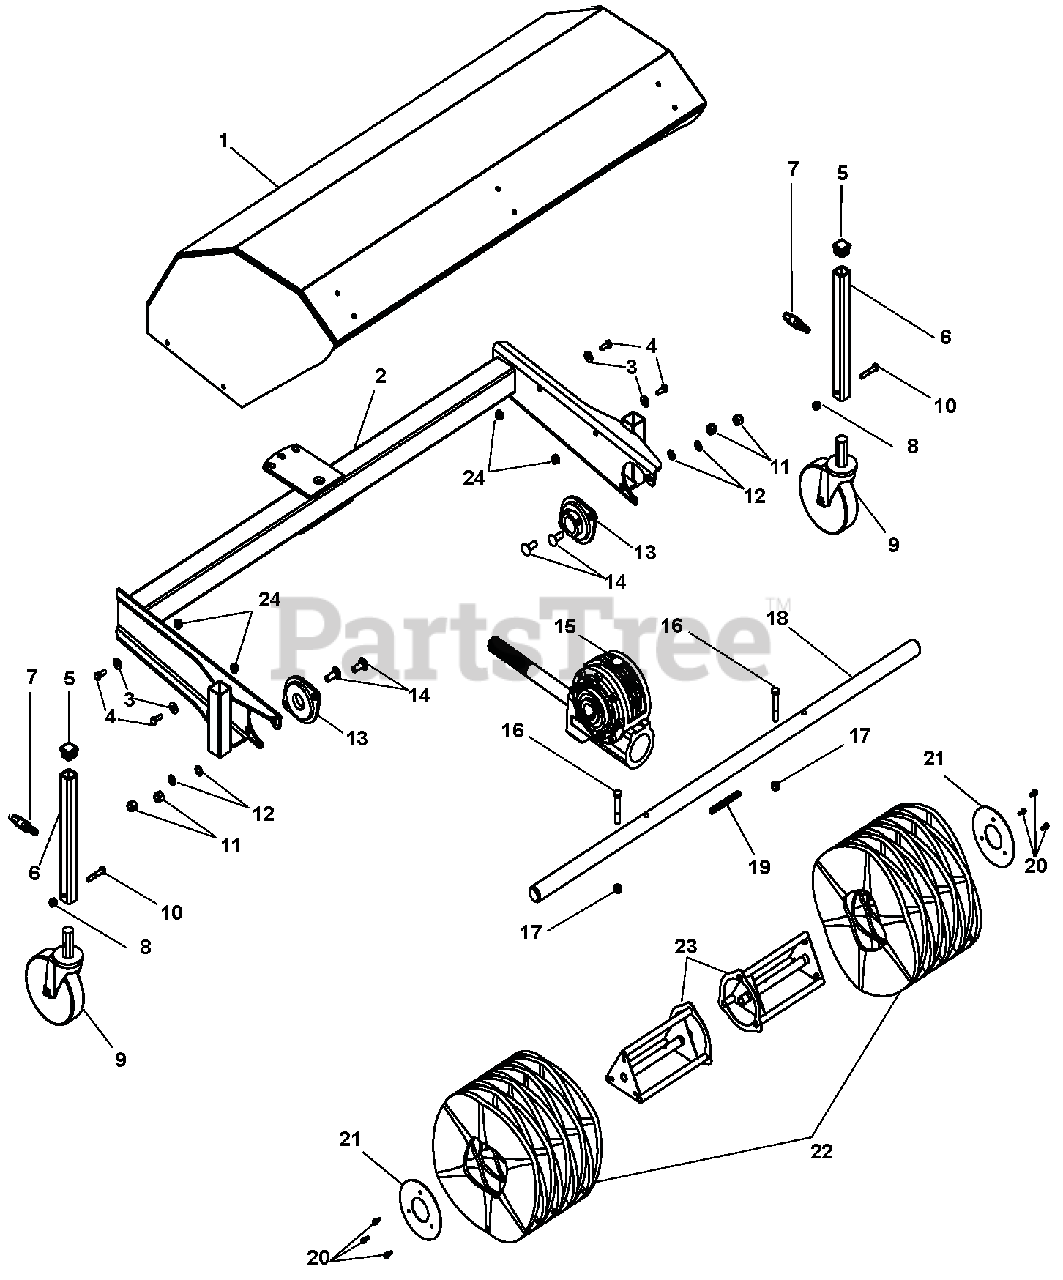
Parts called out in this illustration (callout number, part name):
1	HOOD, 36" BRUSH - W/DECALS
2	FRAME, BRUSH-W.U. 3' BRUSH
3	@WSHR-FL-STL.312X.734X.065 YWZ
4	@BLT-HEX .25-20X.75 GR5 YWZC
5	PLUG, SQUARE-1" PLASTIC
6	LEG, CASTER WHEEL
7	KNOB, BLACK
8	@NUT-LK-NYL .250-20 YWZC
9	CASTER WHEEL,5"X1.250" 7/8 STE
10	@BLT-HEX .25-20X1.50 GR5 YWZC
11	@NUT-LK-NYL .38-16 YWZC
12	WASHER, SAE 3/8
13	BEARING, 1 1/8" FLANGETTE
14	@BLT-RDHDSQNK .38-16X1.00 G5YZ
15	GEARBOX, WORM ALUMINUM-8.25:1
16	@BLT-HEX .31-18X2.25 GR5 YWZC
17	@NUT-LK-NYL .312-18 YWZC
18	SHAFT, THRU 1-1/8 X 3' MCD
19	KEY, SQUARE .25X.25X3 LG
20	HHCS, SERRATED FLANGE 3/8-16X1
21	PLATE, END RETAINER
22	KIT, BRISTLE - SET OF 18
23	KIT-36" BRUSH DRV CORE REPL
24	@NUT-LK-TOP-FLG .25-20 YWZC
